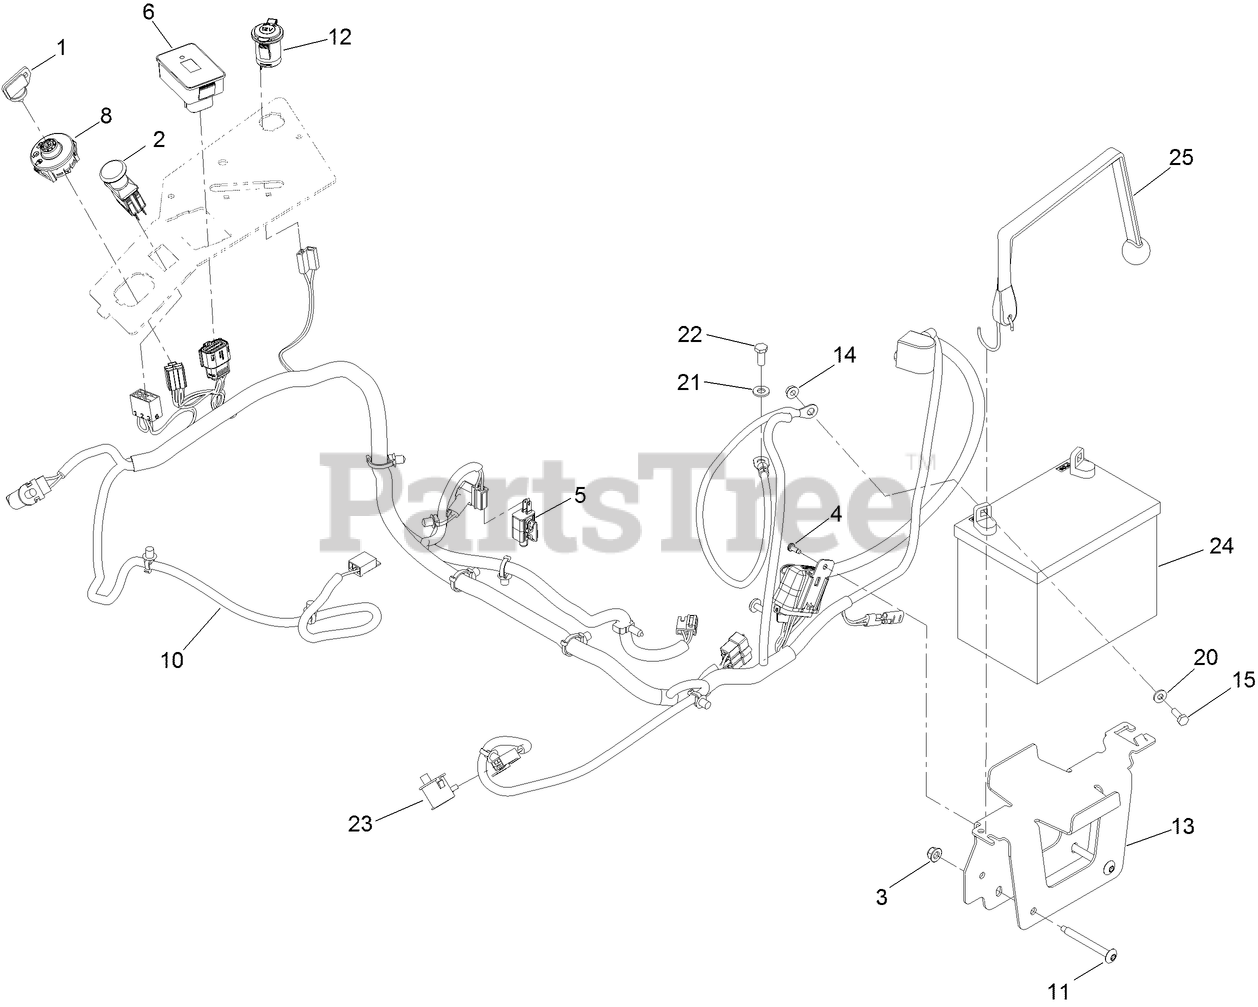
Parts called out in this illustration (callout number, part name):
1	KEY-IGNITION
2	SWITCH-PTO
3	NUT-HF, NI
4	SCREW-FORMING, THREAD
5	SWITCH
6	MODULE ASM
8	SWITCH-IGNITION
10	HARNESS-WIRE
11	SCREW-TORX
12	PORT-POWER, 12V
13	TRAY-BATTERY
14	NUT-HF
15	SCREW-HH
20	WASHER-FLAT
21	WASHER-PLAIN
22	SCREW-HH
23	SWITCH-BAIL
24	BATTERY
25	STRAP-BUNGEE
